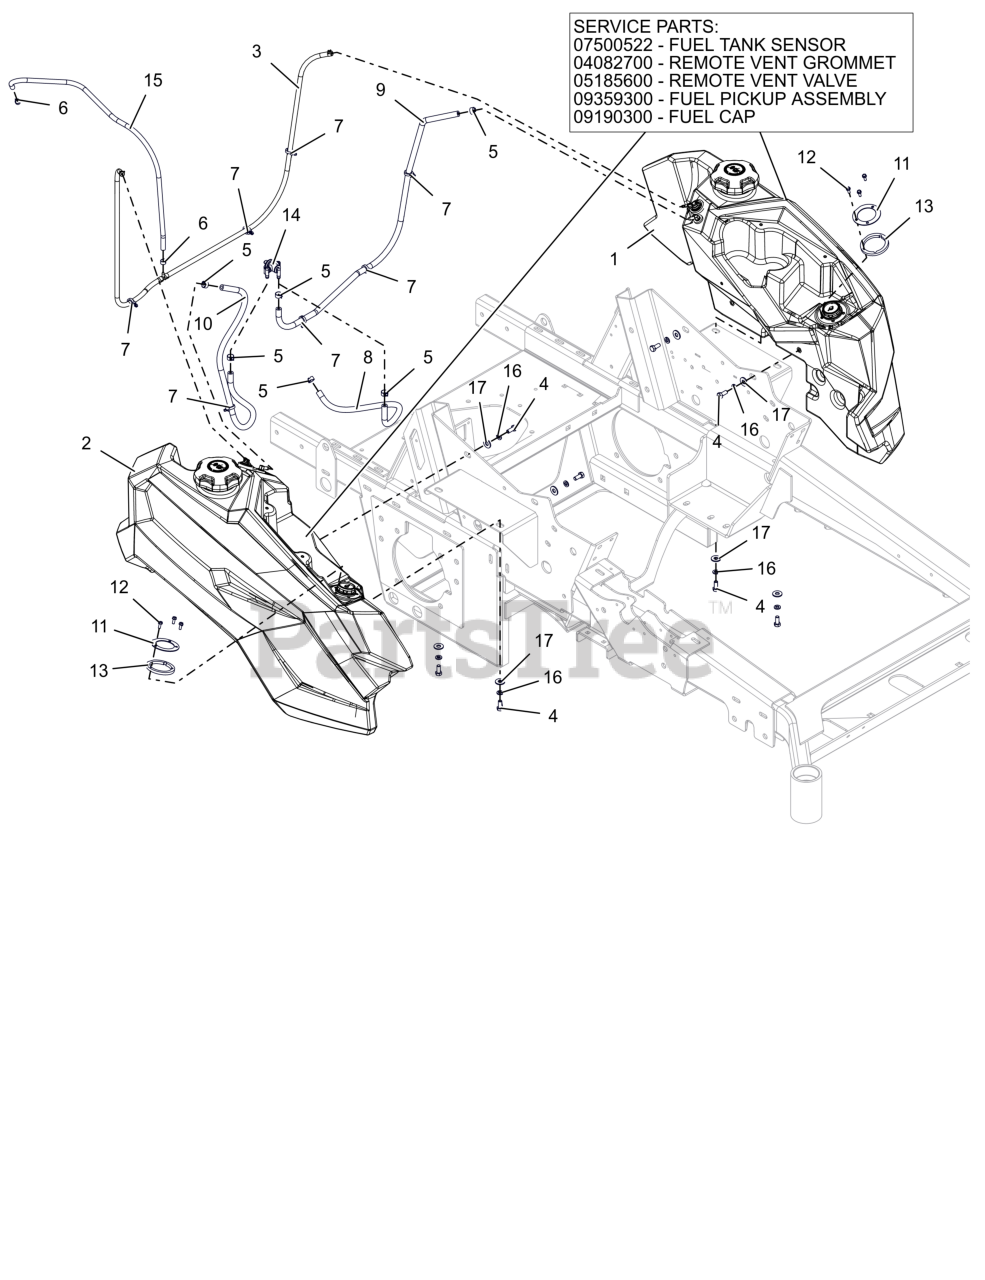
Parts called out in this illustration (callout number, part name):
1	ASM- PT300-500 LH FUEL TANK
1	GAUGE- REMOTE SEALED FUEL
1	GROMMET, REMOTE VENT NITRILE
1	VALVE, COMBINATION VENT 3/16
1	FUEL PICKUP ASSEMBLY
1	CAP, FUEL - 3.50 RATCHET INLET VENT
2	ASM- PT300-500 RH FUEL TANK
2	GAUGE- REMOTE SEALED FUEL
2	GROMMET, REMOTE VENT NITRILE
2	VALVE, COMBINATION VENT 3/16
2	FUEL PICKUP ASSEMBLY
2	CAP, FUEL - 3.50 RATCHET INLET VENT
3	ASM- PT300/500/600 VENT LINE
4	BLT,HEX .31-18X.75 G5 ZCC
5	CLAMP, FUEL LINE
6	CLAMP-HOSE, SPRING .188
7	CLIP- PUSH-IN X-MAS TREE CABLE
8	1 INCH OF HOSE, .25 LOW-PERM BULK GAS
9	1 INCH OF HOSE, .25 LOW-PERM BULK GAS
10	1 INCH OF HOSE, .25 LOW-PERM BULK GAS
11	RETAINER, FUEL GAUGE (BLACK)
12	SCR-MCH 10-24X.50 HWHSTAINLESS
13	SPCR, FUEL GAUGE RETAINER (BLACK)
14	VALVE, FUEL - WITH MAGNET
15	HOSE, .188 30R7 BULK
16	WSHR,LK-REG .312X.078 ZCC
17	WSHR,FLT .375X.875X.083 ZCC
